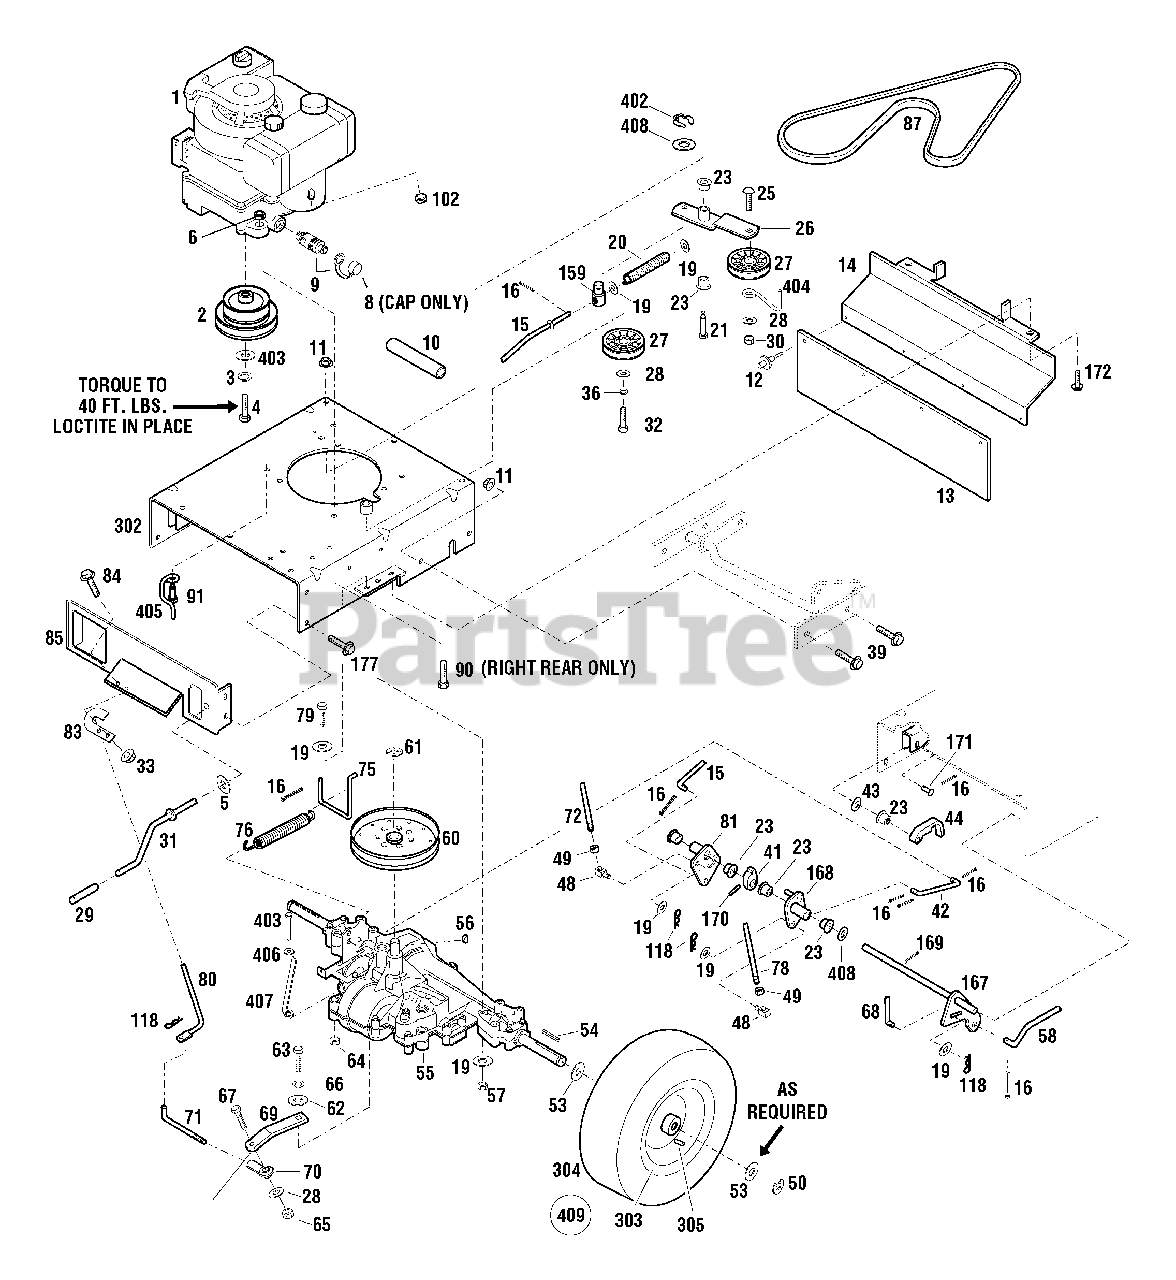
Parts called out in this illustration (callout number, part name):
1	Engine, Electric Start
2	Engine Pulley
3	Lock Washer, 7/16
4	Bolt, 7/16-20 x 1-3/4
5	Washer, Nylon
6	Ground Wire Jam Nut, 3/8-16
8	Oil Valve Cap
9	Oil Valve
10	Oil Drain Hose
11	Flange Locknut, 3/8-16
12	Pop Rivet, 3/16
14	Flap Bracket
15	Lower Transmission Rod
16	Cotter Pin, 3/32 x 5/8
19	Flat Washer, 5/16
20	Compression Spring
21	Shoulder Bolt
23	Nyliner, 1/2
25	Carriage Bolt, 3/8-16 x 1-3/4
27	Idler Pulley
28	Flat Washer, 3/8
29	Plastic Grip
30	Top Locknut, 3/8-16
31	Lift Crank Assembly
32	Bolt, 3/8-16 x 1-3/4
33	Flange Locknut, 1/4-20
36	Lock Washer, 3/8
39	Flange Lock Screw, 3/8-16 x 1
41	Interlock Cam
42	Lower Brake Rod
43	Washer, Flat 1/2
44	Interlock Latch
48	Swivel Block
49	Jam Nut, 5/16-18
50	Retaining Ring
53	Special Washer
54	Square Key, 3/16 x 2-1/2
55	Transmission Assembly, Model 915-027
56	Woodruff Key, 3/16 x 3/4
57	Flange Nut, 5/16-18
58	Lower Blade Rod
60	Transaxle Pulley
61	Retaining Ring
62	Flat Washer, 1/4
63	Screw, 1/4-28 x 3/4
64	Flange Locknut, 1/4-20
65	Locknut, 3/8-16
66	Lock Washer, 1/4
67	Screw, 3/8 x 1-1/4
68	Upper Blade Rod
69	Transmission Arm
70	Ball Joint
71	Shift Link Rod
72	Upper Transmission Rod
75	Spring Attachment Rod
76	Extension Spring
78	Upper Brake Rod
79	Screw, 5/16-18 x 2-3/4
80	Shift Rod
84	Flange Lock Screw, 1/4-20 x 1/2
85	Backplate
90	Thread Forming Screw, 3/8-16 x 1-1/2
91	Thread Forming Screw, 3/8-16 x 1
102	Hex Nut, 1/4-20
118	Hair Pin, 5/64
167	Pivot Shaft Assembly
170	Drive Pin, 5/32 x 1
171	Clevis Pin, 1/2 x 1-1/4
172	Screw, 5/16-12 x 3/4
177	Flange Screw, 5/16-18 x 3/4
304	Tire
305	Valve Stem
400	Loctite 242, 0.02 oz. Tube
402	Clip Ring
403	Screw, 1/4-20 x 2.0
404	Belt Guide
405	Belt Guide
406	Flat Washer
408	Flat Washer
409	Wheel Assembly
